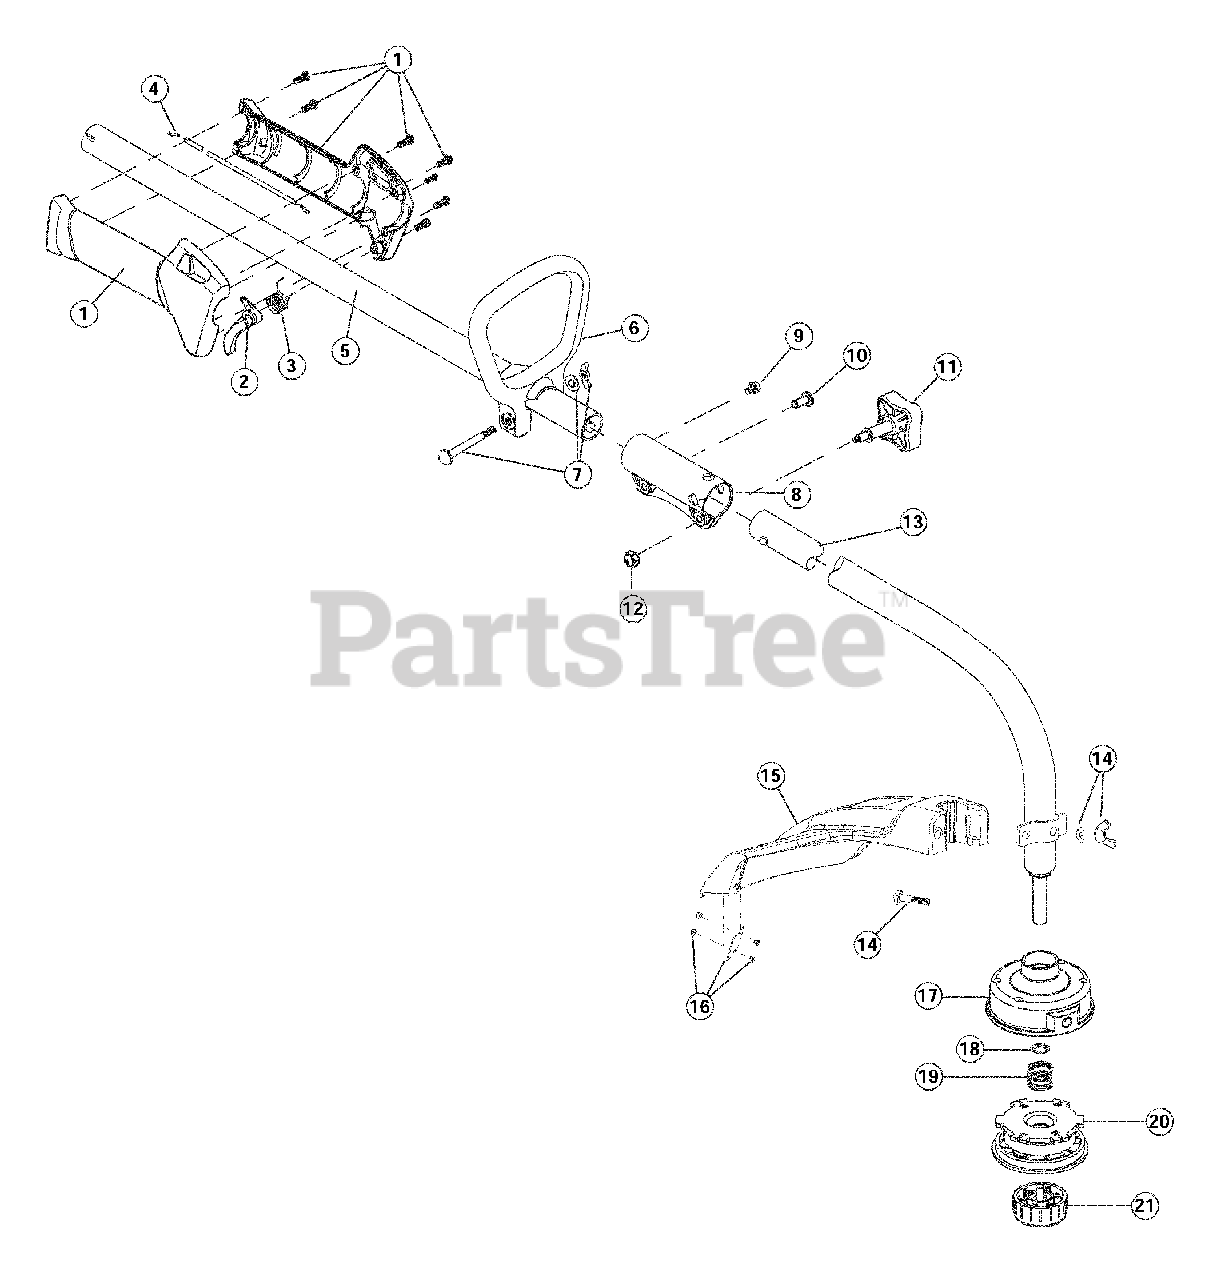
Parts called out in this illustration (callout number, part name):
1	Throttle Housing Assembly
2	Throttle Trigger Spring
3	Throttle Trigger
4	Throttle Cable
5	Upper Drive Shaft Housing Assembly
6	D-Handle
7	Handle Hardware
8	Split Boom Coupler
11	Adjustment Knob
12	Knob Retaining Nut
13	Lower Drive Shaft Housing Assembly
14	Guard Mounting Hardware
15	Guard
16	Blade Assembly
17	Outer Spool Assembly
20	Inner Reel
21	Bump Head Knob Assembly
